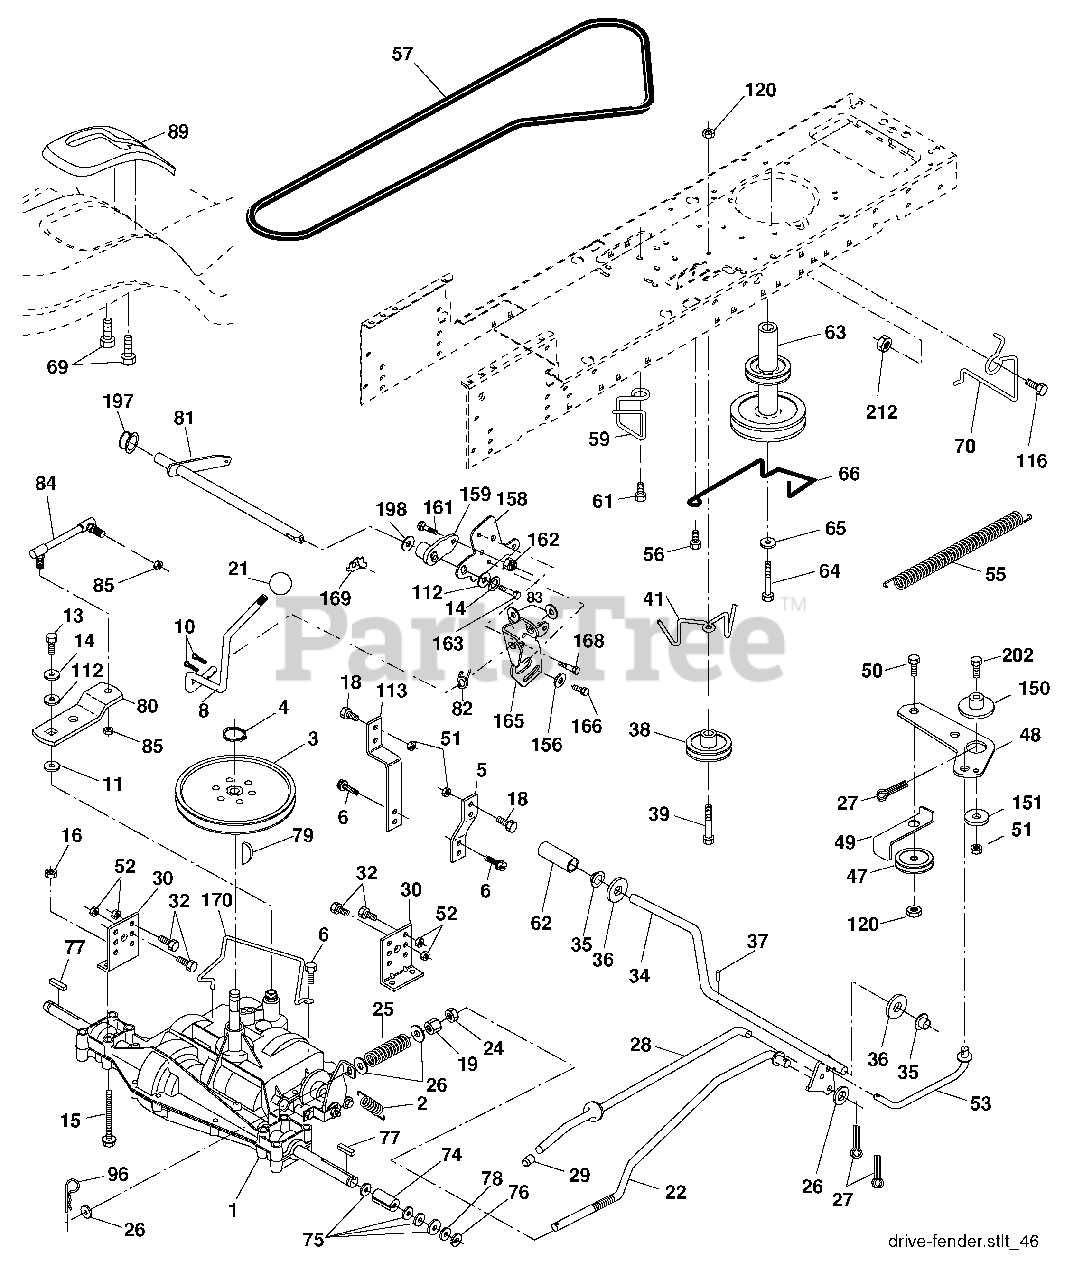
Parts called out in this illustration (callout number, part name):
1	Transaxle Dana D4360-139 (See Breakdown)
2	Spring Brake Return
3	Pulley Transaxle
4	Ring Retainer
5	Strap Torque 30 Degrees
6	Screw 5/16-18 x 3/4
8	Rod Shift Fender Adjust
10	Pin Cotter 1/8 x 1 CAD
11	Washer Plate Shift
13	Bolt 1/4-28 unf Gr. 8 W/Patch
14	Washer Lock Hvy Helical
15	Bolt Hex FLGHD 5/16-18 x Gr. 5
16	Nut Lock Hex W/Ins. 5/16-18 unc
18	Bolt Fin Hex 3/8-16 x 1 Gr. 5
19	Nut Lock Hex W/Wsh 3/8-16 unc
21	Knob
22	Rod, Brake
24	Nut, Hex Jam 3/8-16 unc
25	Spring, Brake Rod
26	Washer 13/32 x 13/16 Ga.
27	Pin Cotter 1/8 x 3/4 CAD.
28	Rod, Parking Brake
29	Cap, Parking Brake
30	Bracket, Transaxle
32	Bolt Hex Hd 5/16-18 unc x 3/4
34	Shaft, Foot Pedal
35	Bearing, Nylon
36	Washer
37	Pin, Roll
38	Pulley, Composite, Flat
39	Bolt Fin Hex 3/8-16 x 2-3/4
41	Keeper, Belt Idler
47	Pulley, Idler, V-Groove
48	Bellcrank, Clutch
49	Retainer, Belt
50	Bolt Carr 3/8-16 x 1-1/2
51	Nut Crownlock 3/8-16 unc
52	Nut, Crownlock 5/16-18 unc
53	Link, Clutch
55	Spring, Return, Clutch
56	Screw 3/8-16 x 1-1/4
57	V-Belt
59	Keeper, Center Span
61	Screw, 3/8-16 x .875
62	Cover, Pedal
63	Pulley, Engine
64	Bolt Hex 7/16-20 x 4 Gr. 5-1.5
65	Washer Lock 7/16
66	Keeper Belt Engine Hydro
69	Screw Hex Wsh Hi-Lo 1/4 x 1/2 unc
70	Keeper Belt Engine
74	Spacer
75	Washer 25/32 x 1-1/4 x 16 Ga.
76	E-Ring
77	Key, Square
78	Washer 25/32 x 1-5/8 x 16 Ga.
79	Key Woodruff
80	Arm Shift
81	Shaft Asm Cross Tapered
82	Spring Torsion
83	Washer 17/32 x 3/4 x 16 Ga.
84	Link Transaxle
85	Nut Lock Center 1/4-20
89	Console, Shift
96	Retainer Spring 1" Zinc/Cad
112	Washer 9/32 x 3/4 x 10 Ga.
113	Strap Torque 90 Degrees
116	Bolt Rdhd Sqneck 3/8-16 x 1.25
120	Nut Lock Flg 3/8-16
150	Spacer Retainer
151	Washer 13/32 x 2 x 10 Ga.
156	Washer Srrted 5/16 ID x 1.125
158	Bracket Shift Mount
159	Hub Shift
161	Bolt Rdhd Sqnk 1/4-20 x 3/4 Gr. 5
162	Nut Crownlock 1/4-20 unc
163	Bolt Hex Fin 1/4-20 unc x 1 Gr. 5
165	Bracket Pivot Lever
166	Screw 5/16-18 x 5/8
168	Bolt Shoulder 5/16-18 x .561
169	Plate Fastening
170	Keeper Belt T/A
197	Nyliner Snap-In 5/8’’ID
198	Washer Nyl
202	Bolt Carr Sh 3/8-16 x 1-3/4 Gr. 5
212	Nut Hex Flg. Lock
